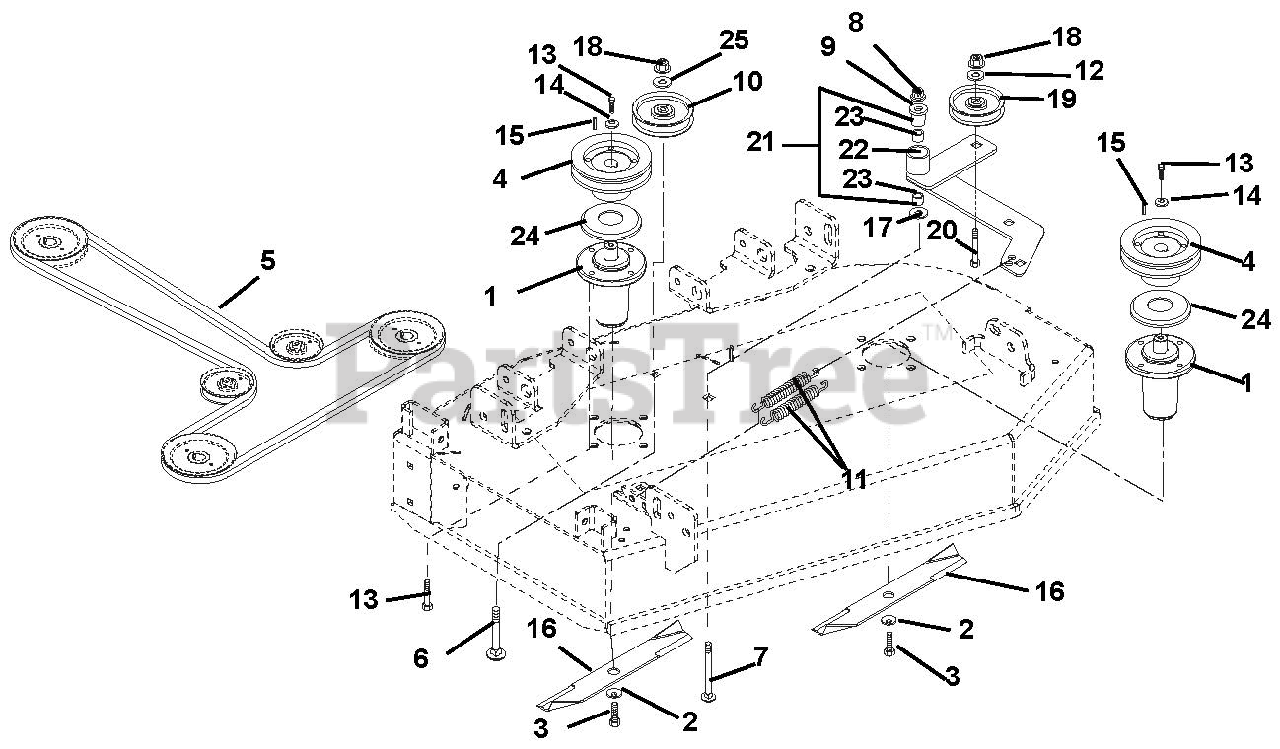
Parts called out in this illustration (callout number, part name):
1	Assembly, Maintenance Free Spindle
2	Washer-Bellville .63 x 1.625 x .14
3	Bolt-Hex .62-18 x 1.75 Grade 8
4	Sheave, 5.00 Spindle (1.00 I.D.)
5	V-Belt, B-Section 49.68 x .62548.80 x .625
6	Bolt-Round Head Square Neck .38-16 x 3.0 Grade 5
7	Bolt-Round Head Square Neck .50-13 x 3.50 Grade 5
8	Nut, Nyloc Flange .50-13
9	Bearing, Pedestal
10	Idler-Flat 4.00 x .38 (2.00 W)
11	Spring, Extension
12	Washer-Flat-Steel .375 x 1.125 x .065
13	Bolt, Hex .38-16 x 1.00 EP30
14	Washer-Flat-Steel .406 x 1.50 x .245
15	Key, Square .25 x .25 x 1.00
16	Blade, Mower Hi-Lift
16	Blade, Mulching 50" Mower
17	Washer, Flat Steel .531 x 1.250 x .100
18	Nut, Nyloc Flange 3/8-16
19	Idler, Flat 4.00 x .38 (1.00 W)
20	Bolt, Round Head Square Neck .38-16 x 2.00 Grade 5
21	Assembly, Idler Pivot Arm
22	Weldment, Idler Pivot Arm
23	Bearing, 1.00 x 1.12 x .75
24	Slinger, Dust
25	Seal, Idler Bearing
